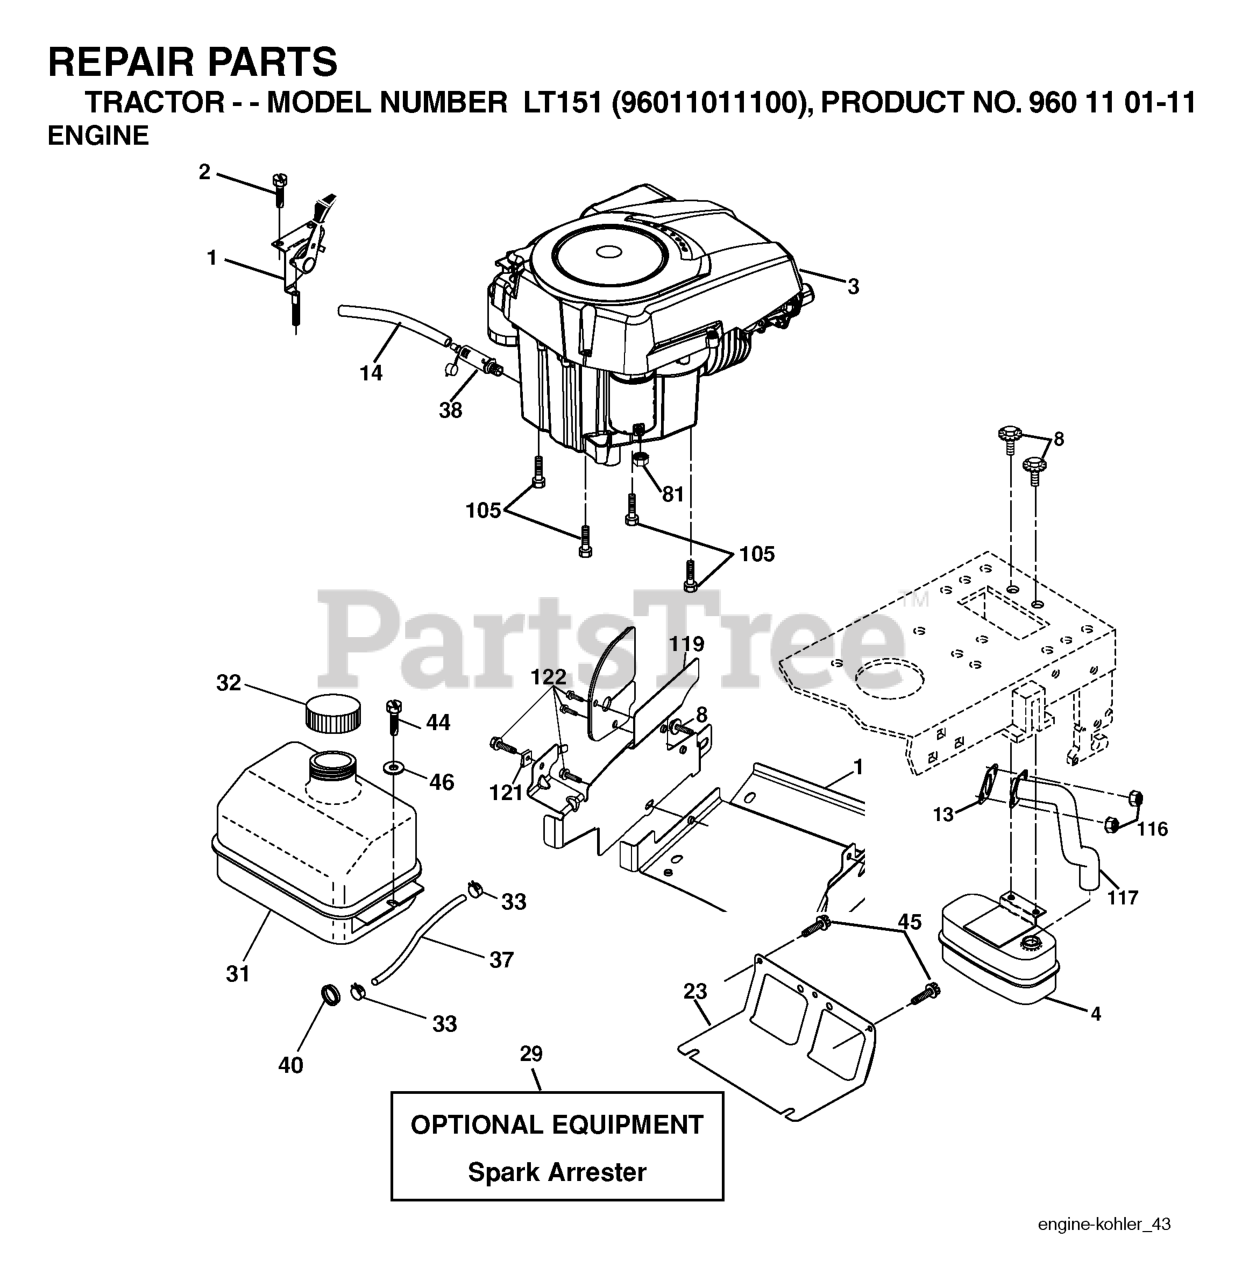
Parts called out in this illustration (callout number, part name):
2	SCREW
4	MUFFLER.SINGLE.CYL.KOHL/B&S
8	BOLT.5/16-18UNCX3/4 W/SEMS.BLK
13	GASKET.EXHAUST.KOHLER
14	TUBE, DRAIN OIL ASM.
23	SHIELD.BROWNING.DBR.GUARD
29	KIT.SPARK ARRESTOR 794945 B&S
31	TANK.ASM.FUEL.FRONT.W/CAP
32	FUEL CAP
33	HOSE CLAMP
37	LINE.FUEL.20
38	PLUG DRAIN OIL EASY
40	BUSHING.SNAP.NYL.BLK.
44	SCREW HEXWSHR 1/4-20X3/4
45	SCREW, 3/8-16X3/4
81	NUT
105	SCREW 3/8-16X1
116	NUT.HEX.FLANGE.TOPLOCK
117	RP.TUBE.EXHAUST.KOHL.COURAGE
122	SCREW, 5/16-18 X 1/2
123	SCREW.1/4-20X5/8
